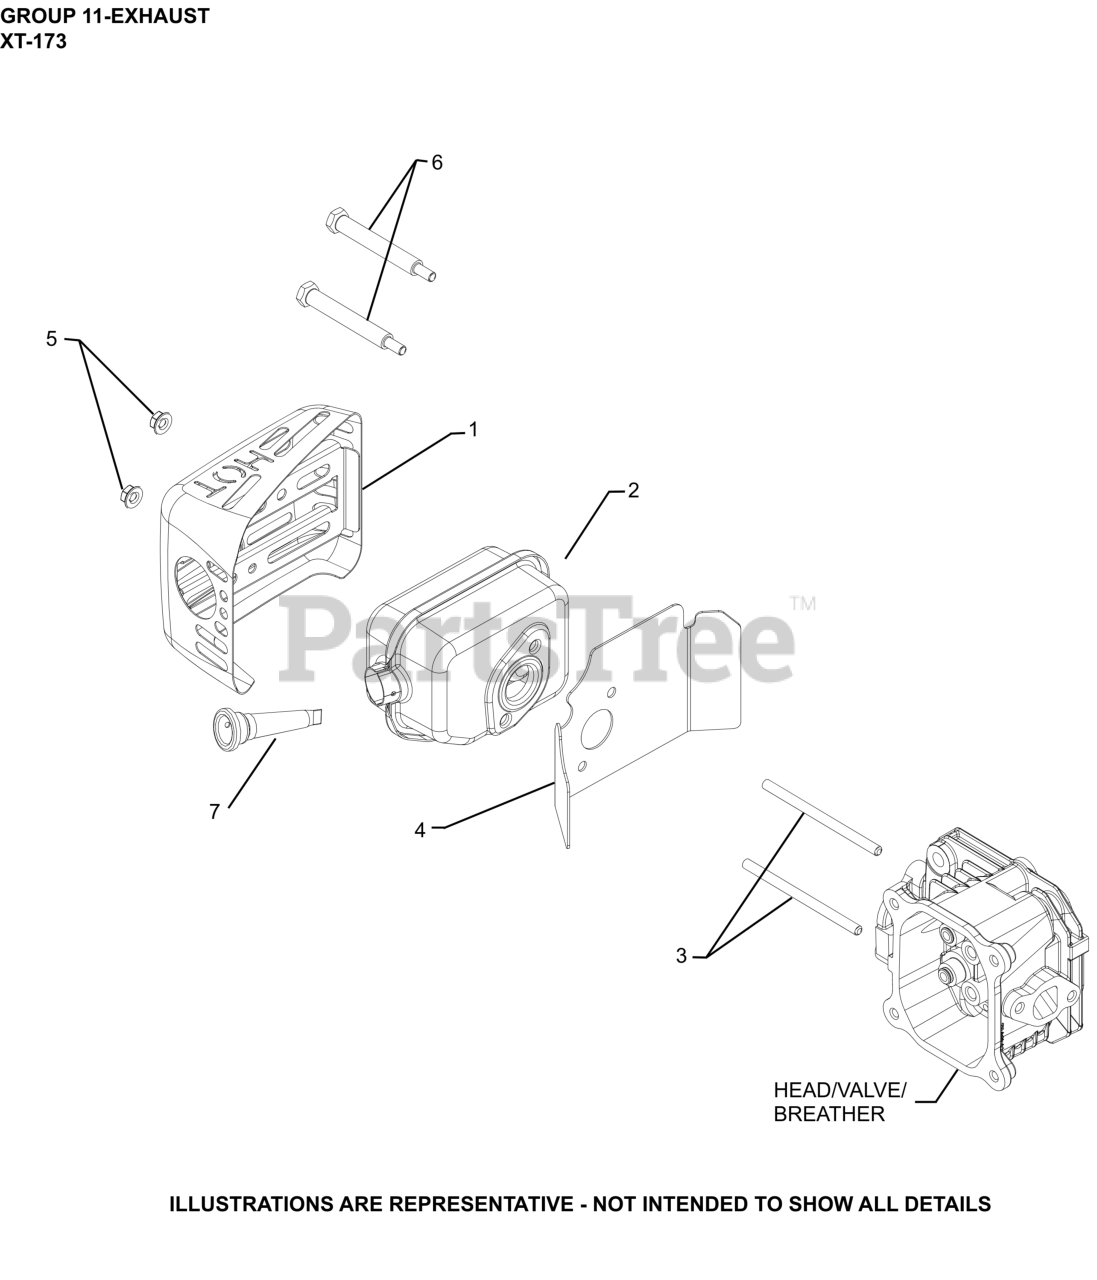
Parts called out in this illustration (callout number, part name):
1	GUARD, MUFFLER
2	KIT, MUFFLER
3	STUD (M6)
4	GASKET, MUFFLER-(#1404155S)
5	NUT, HEX FLANGE LOCK (M6)
